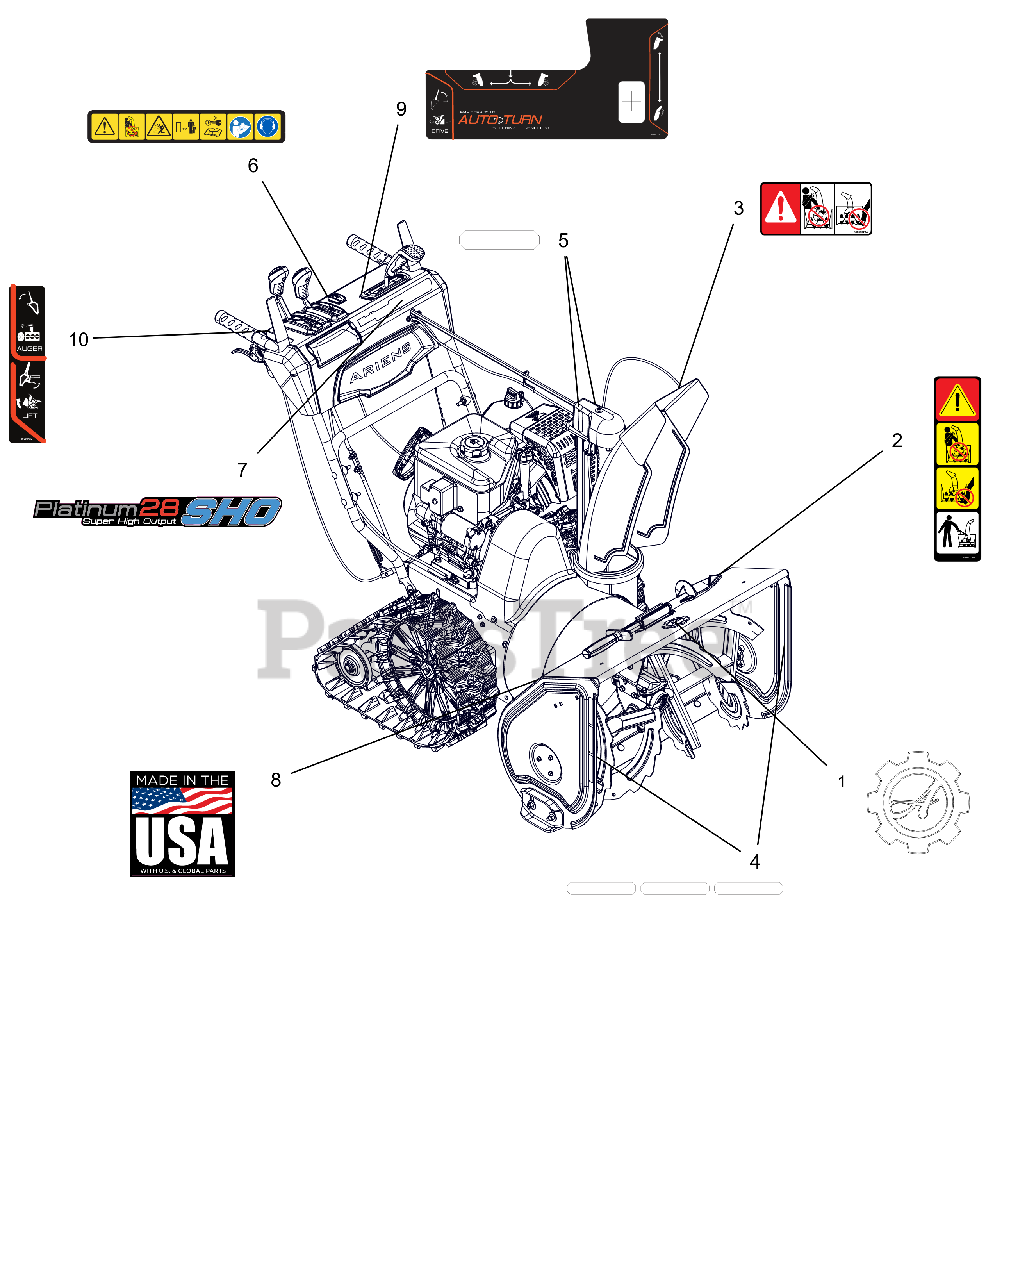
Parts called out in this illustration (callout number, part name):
1	DECAL, ARIENS-GEAR BADGE -THK
2	DECAL, DANGER - ROTATING PARTS
3	DECAL, DANGER
4	DECAL,REFLECTIVE,HOUSING
5	DECAL,REFLECTIVE,GEAR COVER
6	DECAL,DASH - SAFETY
7	DECAL, DASH, PLATINUM 28 SHO
8	DECAL, MADE IN USA
9	DECAL,CONTROL-LG QT2
10	DECAL,CONTROL-RH TRACK
